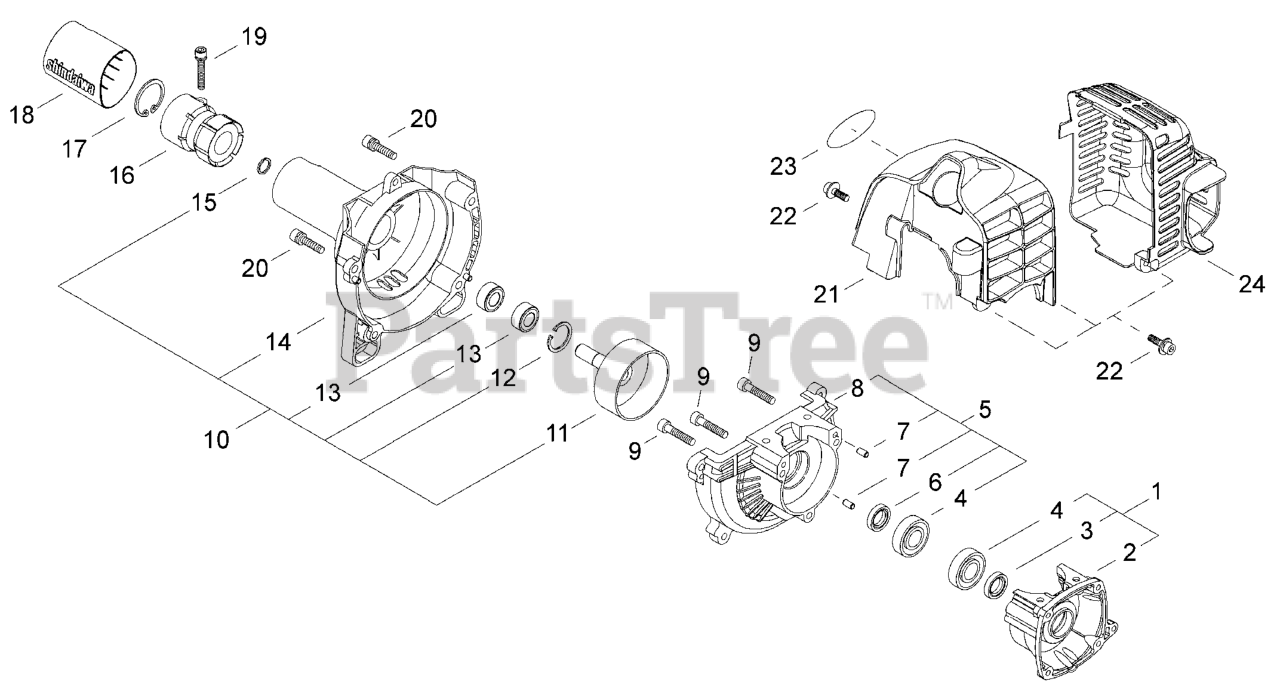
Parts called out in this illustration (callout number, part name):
2	CRANKCASE S
2-1	CRANKCASE ASSY, S
3	SEAL, OIL 12
4	BEARING, BALL 6001 C3
5	CRANKCASE ASSY, M
6	SEAL, OIL 12
7	PIN, LOCATING ?4x8
8	CRANKCASE M
9	BOLT 5x25
10	COVER ASSY, FAN
11	DRUM, CLUTCH
12	RING, SNAP ?26
13	BEARING, BALL 6000DDU
14	COVER, FAN
15	RING, SNAP WR10
16	CUSHION, AV
17	RING, SNAP ?40
18	PROTECTOR
19	BOLT M5x22
20	BOLT M5x18
21	COVER, ENGINE
22	BOLT M4x16
23	LABEL - MODEL 242
24	COVER, MUFFLER
